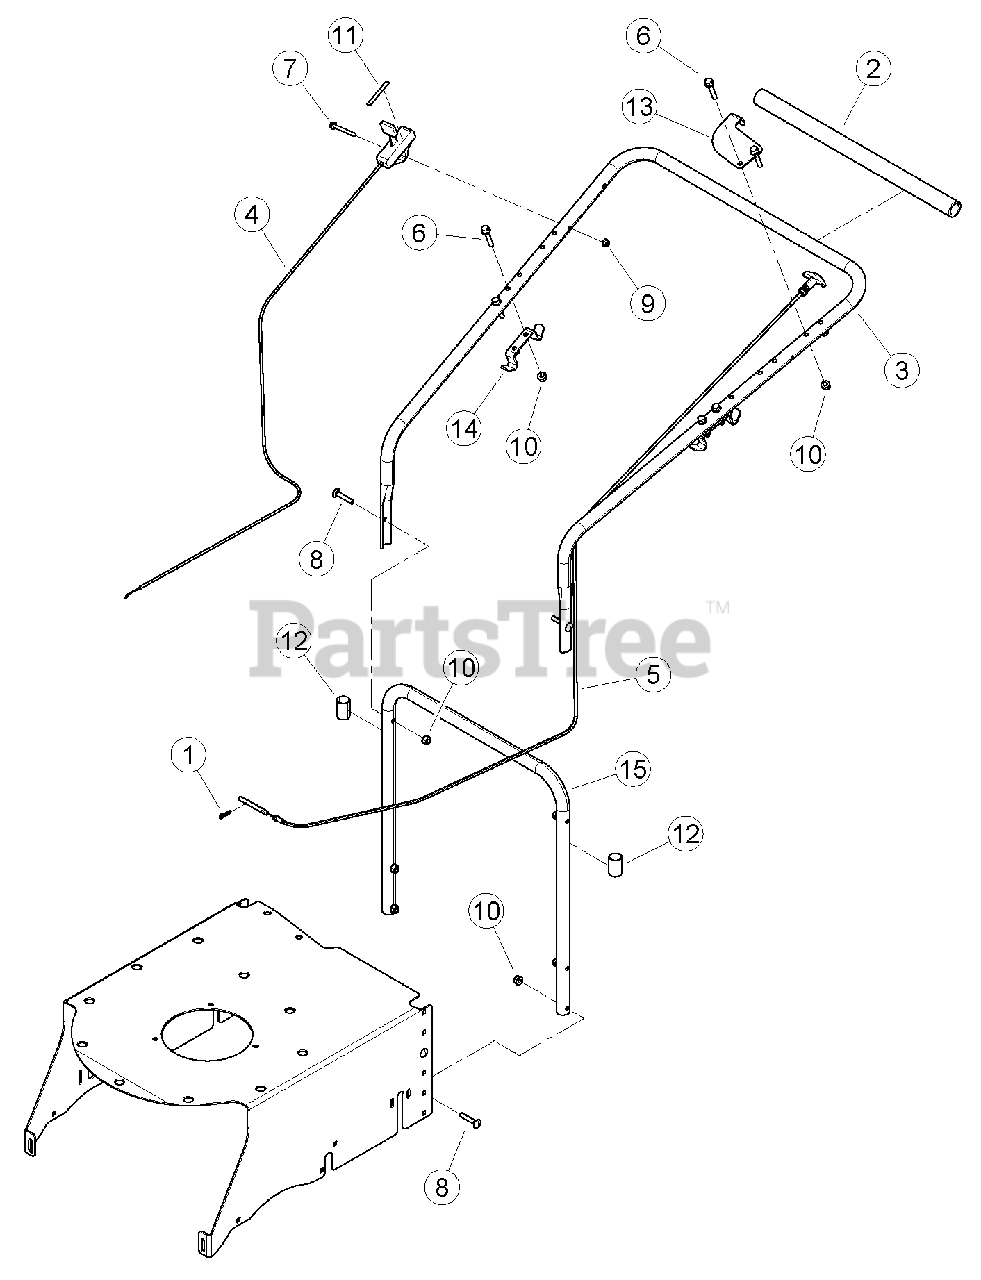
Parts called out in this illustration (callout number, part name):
1	CLIP, HAIRPIN ZP
2	PAD, FOAM HANDLEBAR
3	HANDLE BAR, BEARVAC UPPER
4	CONTROL, THROTTLE
5	CONTROL, HEIGHT ADJUSTMENT
6	BOLT, 5/16 X 1-3/4 FLANGE NC
7	BOLT, 1/4 X 2 FLANGE NC
8	BOLT, 5/16 X 1-3/4 GR5 CRG ZP
9	NUT, 1/4-20 NYLOCK FLANGE
10	NUT, 5/16-18 NYLOCK FLANGE
11	DECAL, THROTTLE
12	CAP, 7/8" PLASTIC
13	BRACKET, BEARVAC CABLE MOUNT
14	BRACKET, BAG HANGER
15	HANDLE BAR, LOWER BEARVAC
